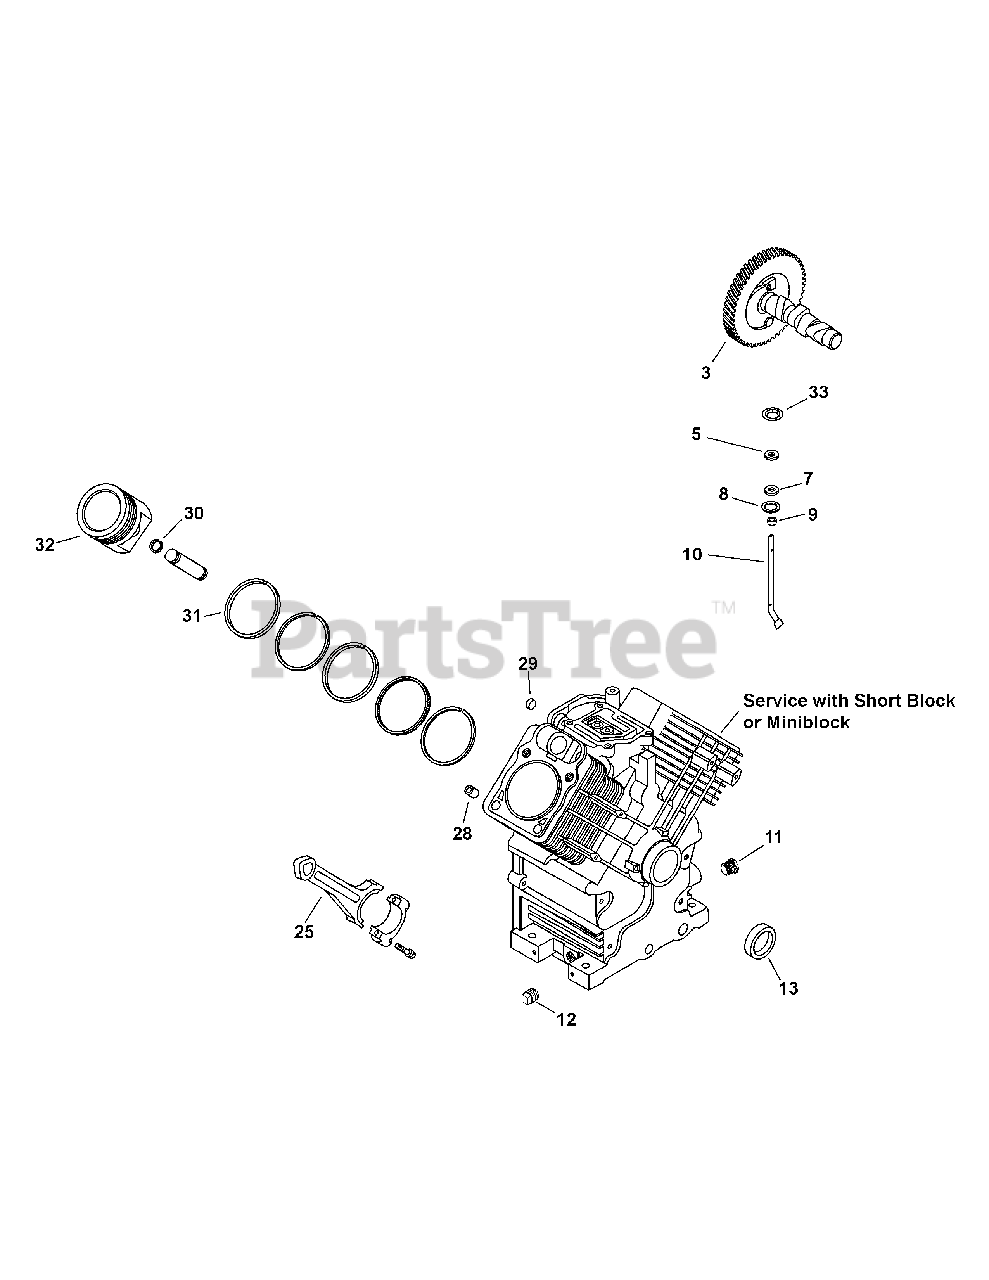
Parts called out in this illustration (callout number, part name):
3	Kit, Camshaft
5	Washer, Flat 9 Mm
7	Seal, Governor Cross Shaft
8	Washer, Flat 11/32"
10	Shaft, Governor Cross
12	Plug, Sq Hd Pipe 3/8"
13	Oil Seal (Helix Lip)
25	Rod Assy, Connecting
28	Pin, Locating
30	Retainer, Piston Pin
31	Ring Set (Std)
31	Ring Set (.08)
31	Ring Set (.25)
31	Ring Set (.50)
32	Kit, Piston Assy W/Ring(Std)77Mm
32	Kit, Piston Assy W/Ring Set(.08)77Mm
32	Kit, Piston Assy W/Ring Set(.25)77Mm
32	Kit, Piston Assy W/Ring Set(.5)77Mm
33	Retainer, Ring
